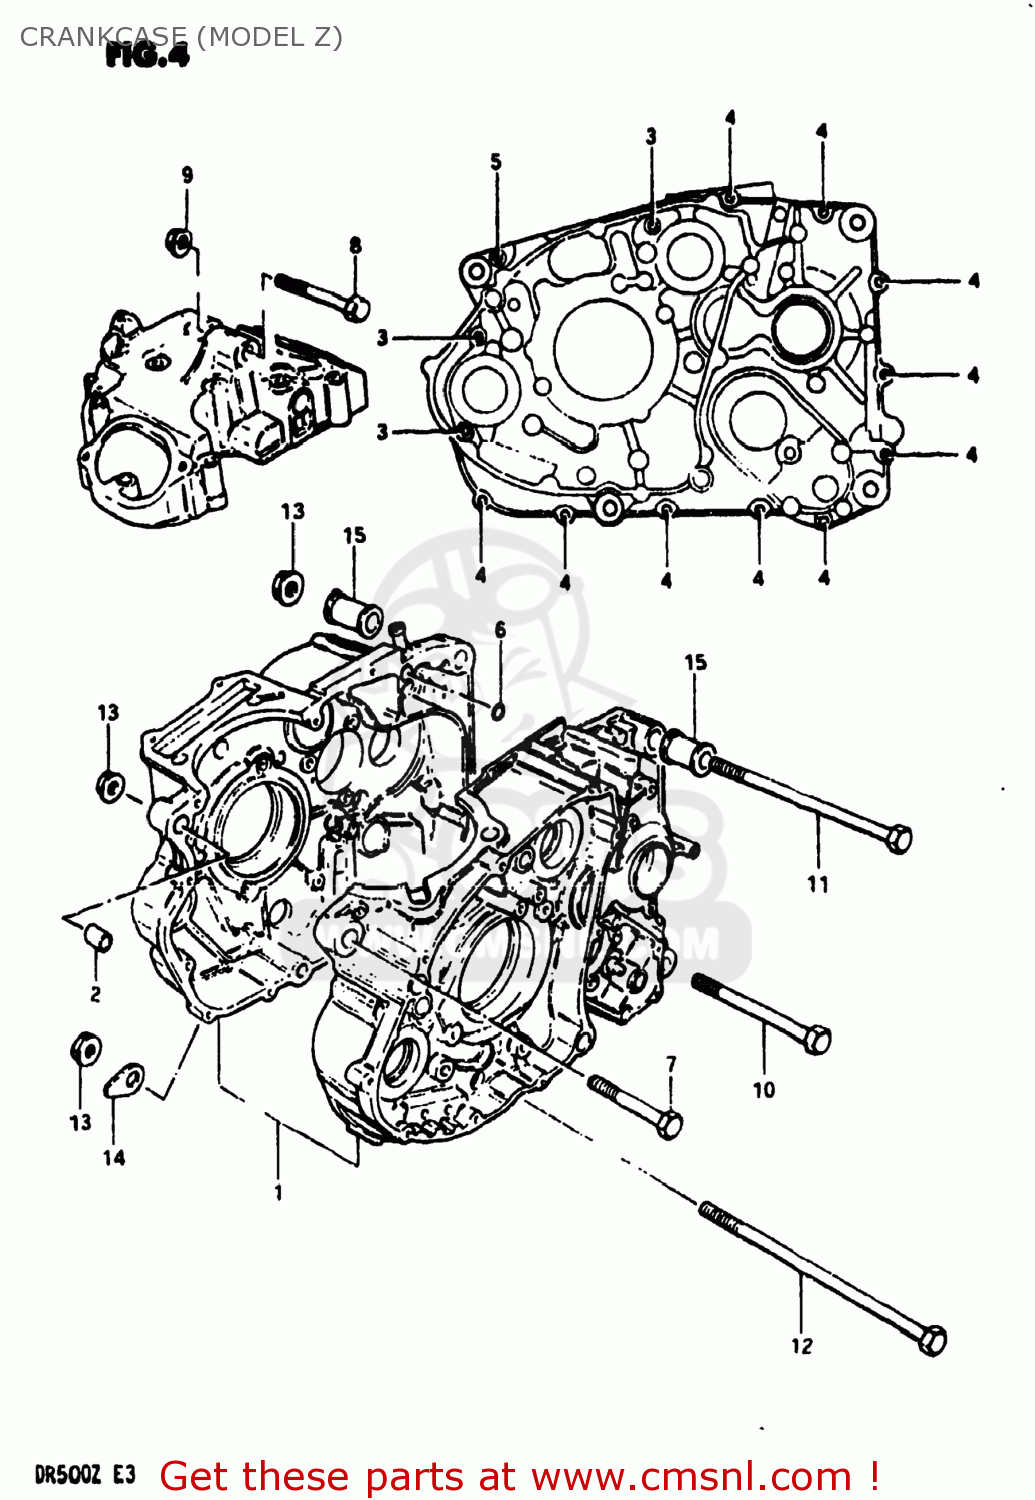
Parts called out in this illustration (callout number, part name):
1	CRANKCASE ASSEMBLY
2	PIN
3	BOLT
4	BOLT (6X40)
5	BOLT (6X30)
6	O-RING
7	BOLT(10X70)
8	BOLT
9	NUT
10	BOLT
11	BOLT
12	BOLT
13	NUT
14	WASHER
15	SPACER
